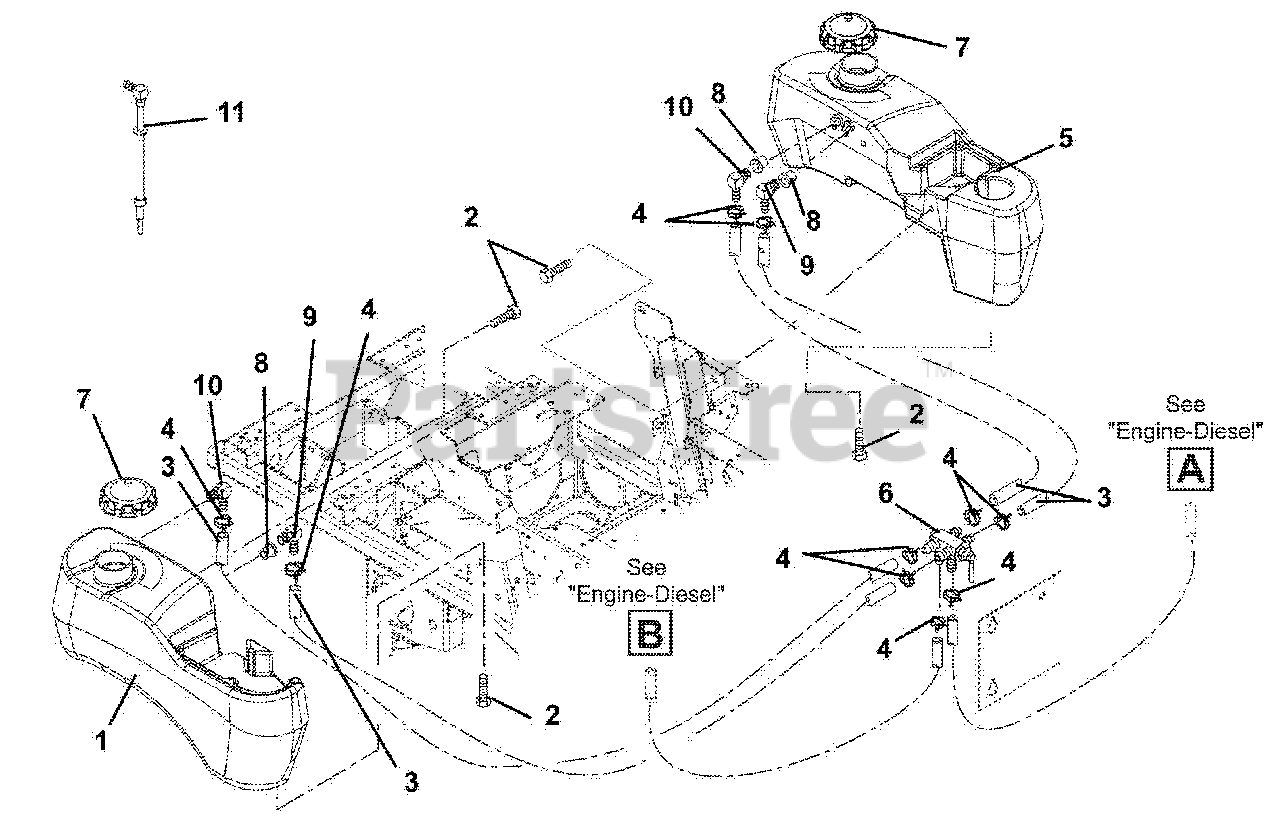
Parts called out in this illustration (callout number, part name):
1	Tank, Fuel-Right Hand
2	Bolt, SEMS .31-18 x .62
3	Hose, .31 ID
4	Clamp, Hose Wire .52/.55
5	Tank, Left Hand Fuel
6	Valve, Fuel
7	Cap, Fuel
8	Grommet, Orange
9	Fitting, Tank
10	Fitting, Tank
11	26" Fuel Line Kit, Diesel (Inside Tank
